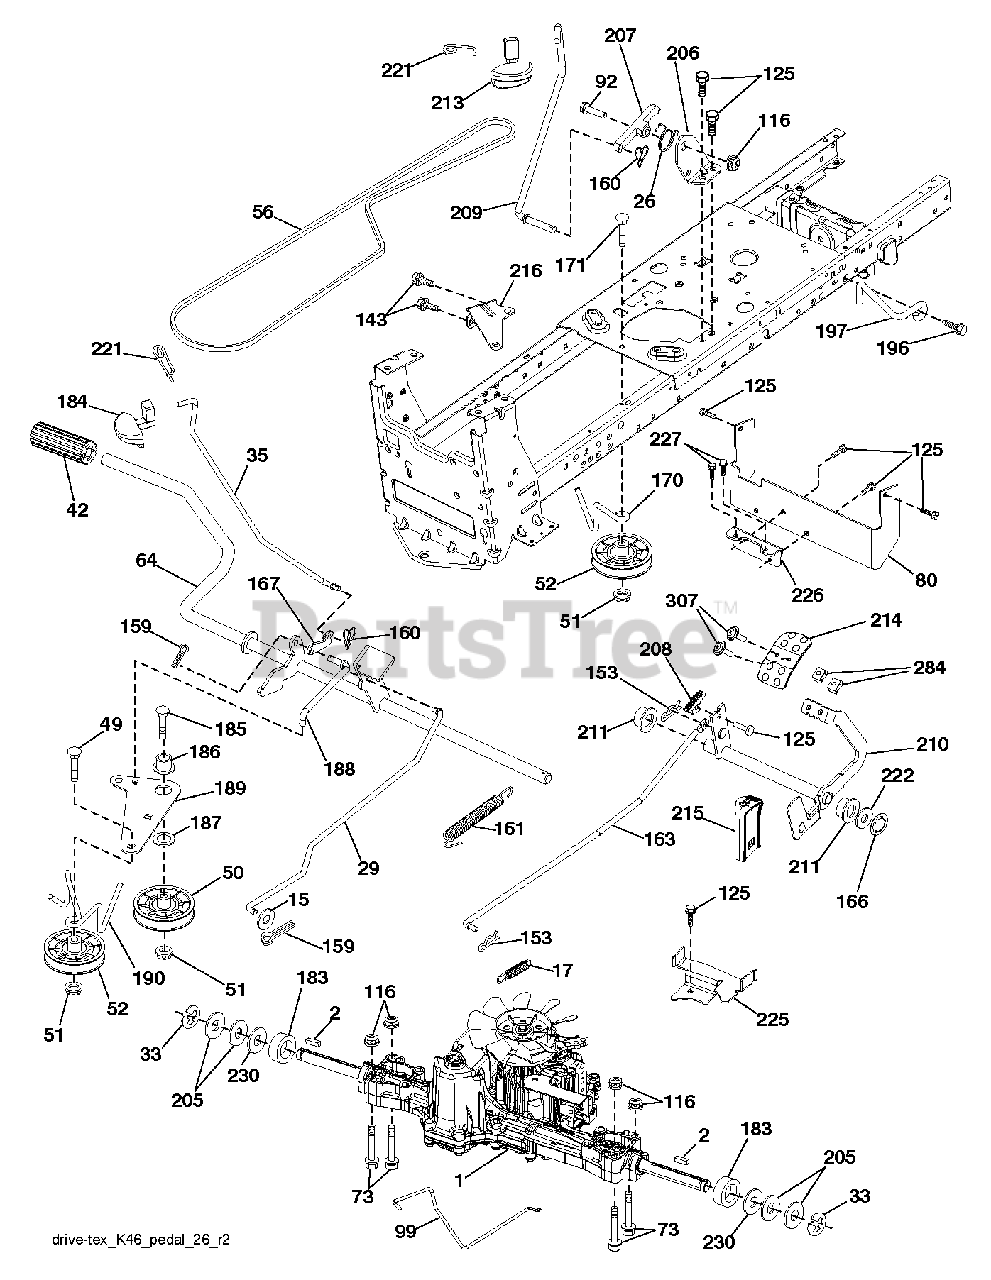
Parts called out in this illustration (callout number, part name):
1	TRANSAXLE(K46BT).PDL.
2	SQUARE KEY
15	WASHER
17	SPRING.BRAKE.K46.GREEN
26	SPRING.RETURN.CRUISE
29	ROD.BRAKE.K46
35	ROD.BRAKE.PARTK.HUSQ.TEX
42	PEDAL COVER T
50	IDLER.FLAT.910.OFFSET
51	NUT LOCK FLG 3/8-16 UNC
52	IDLER.V-GROOVE.910.OFFSET
56	V-BELT.MOWER.92.40.42/K46
64	SHAFT.ASM.PEDAL.BRK.CNTR
80	STRAP TORQUE
92	BOLT
99	ROD.SPRING.BYPASS.K46.LT.Z
116	NUT LOCK HEX FLANGE 5/16-18
125	SCREW
143	SCREW LT
153	RETAINER M
159	COTTER PIN
160	RETAINER CLIP
161	SPRING, RETURN LT
163	ROD.CONTROL.PEDAL.K46
166	NUT.PUSH.625
167	LATCH.BRAKE.SPRING
170	KEEPER.V-IDLER.CENTER.
183	SPACER AXLE
184	HANDLE.PARKG.BRK.HUSQ X667
186	SPACER.RETAINER
187	WASHER 12/32X2X10GA
188	RP LINK.CLUTCH.GROUND.DRIVE
189	BELLCRANK.GROUND.DRIVE.TEX.
190	KEEPER.BELLCRANK.DRIVE
196	SCREW 3/8-16X1
197	LINK.CLUTCH.ANIT-ROTAT
206	BRKT.MOUNT.LATCH.CRUIS
207	LATCH.CONTROL.CRUISE
208	GEAR.SECTOR.CONTROL.CR
209	ROD.CONTROL.CRUISE.GT.
210	ROCKER.ASM.PEDAL.CONTR
211	BEARING.NYLON
213	KNOB.CONTROL.CRUSIE.HU
214	PEDAL.FORWARD.HUSQVARNA.DEALER
215	PEDAL.REVERSE.TEX.GT.4
216	BRACKET.PULLEY.IDLER.W/TEX
221	RETAINER.SPRING.CLIP.H
222	WASHER 21/32 X 1-1/4 X 10 GA.
225	KEEPER.BELT.TRANSAXLE.K46
226	BRACKET.MOUNT.TORQUE.K46.TLT
227	SCREW
230	WASHER.HARDENED
284	NUT.U-CHNL.1/4-20.550DP.350PNL
307	SCREW.MACHINE.CR.1/4-20
